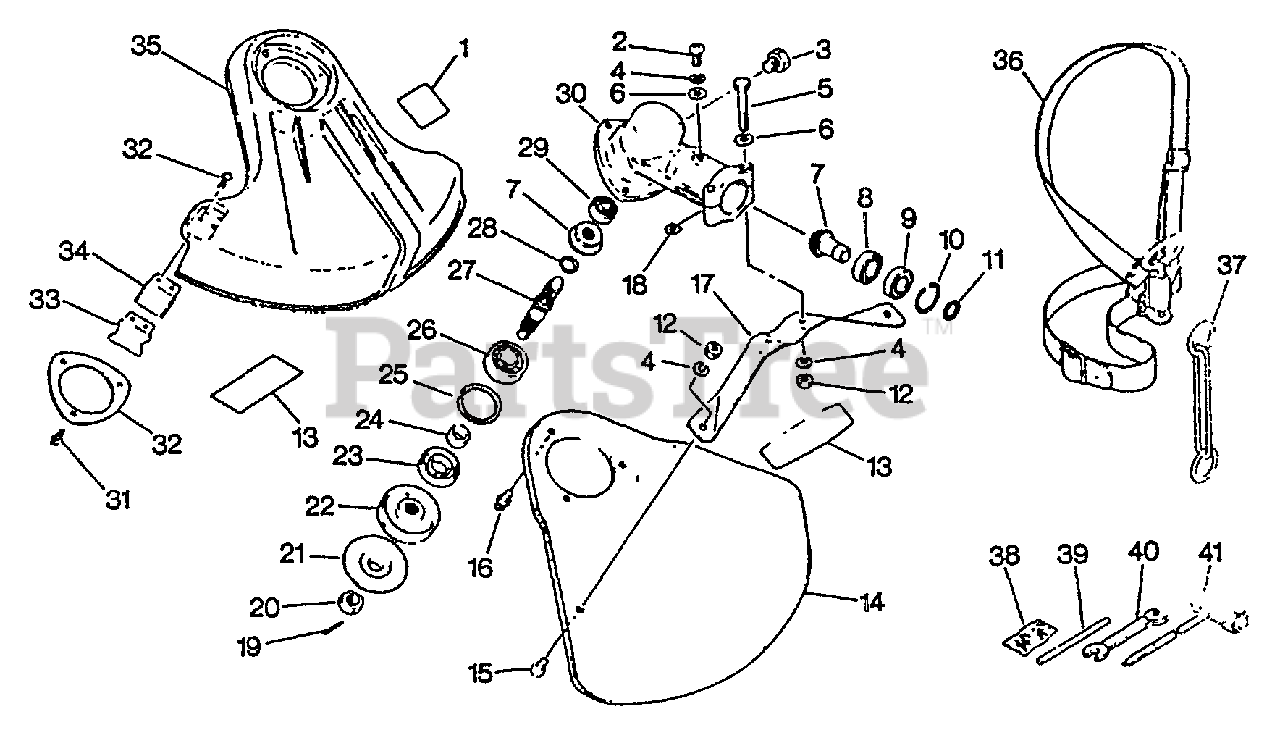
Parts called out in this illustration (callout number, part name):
1	LABEL - CAUTION
2	SCREW - 5X10
3	BOLT - 8X8
4	LOCKWASHER - 5
5	BOLT - 5X35
6	WASHER - 5
7	GEAR SET - BEVEL
8	BEARING, BALL - 6900
9	BEARING, BALL - 6900Z
10	RING, RETAINING - 22
11	RING, RETAINING - 12
13	LABEL - ECHO
14	SHIELD ASSY - PLASTIC
15	SCREW - 5X8
16	SCREW - 5X10
17	BRACKET, SHIELD
19	PIN, SPLIT - 2X22
20	NUT - 10 -- LEFT HAND
21	ADAPTOR, BLADE - LOWER
22	ADAPTOR, BLADE - UPPER
23	SEAL, OIL
25	RING, RETAINING - 32
26	BEARING, BALL - 6201
27	GEAR - SHAFT
28	RING, RETAINING - 10
29	BEARING, BALL - 609
30	CASE, GEAR
31	SCREW - 5X16
32	PLATE, SHIELD
33	GUARD
34	KNIFE, TRIMMER LINE
35	SHIELD, DEBRIS - PLASTIC
35	DEBRIS SHIELD KIT
36	SHOULDER STRAP ASSY
38	PIN, SPLIT - 2X22
39	LOCKING TOOL
40	SPANNER - 8X10mm
41	T-WRENCH - 17X19mm
